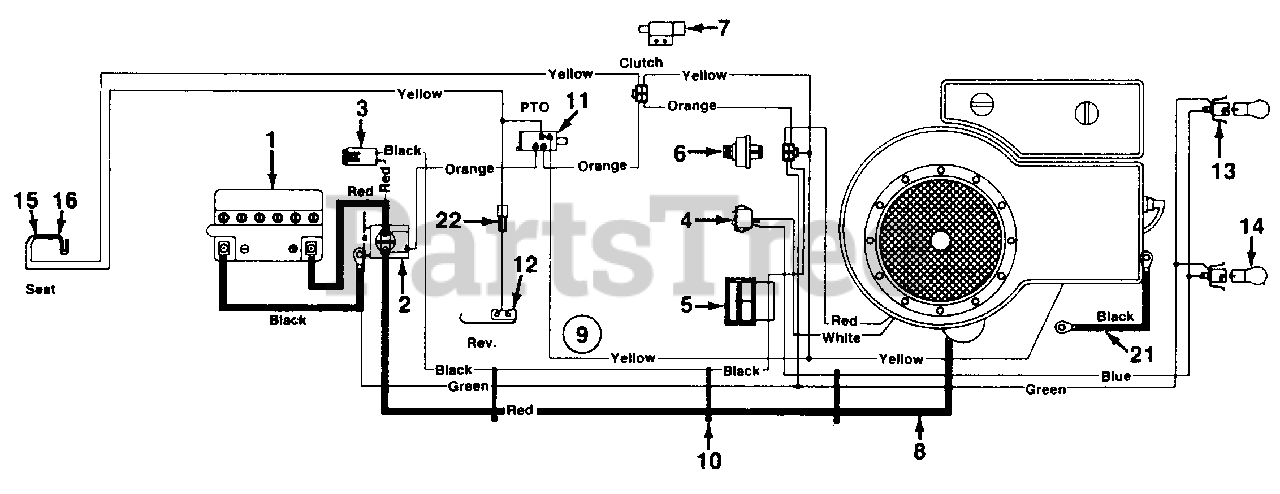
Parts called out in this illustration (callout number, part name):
1	Battery
2	Solenoid
3	Fuse 7.5 Amp
4	Light Switch
5	Ammeter
6	Ignition Switch
7	Safety Switch (Clutch)
8	Electric Wire 30" Lg.
9	Wire Harness
10	Cable Tie
11	Safety Switch (Deck)
12	Safety Switch (Reverse)
13	Twist Lock Bulb Socket
14	Bulb
15	Safety Switch (Seat)
16	Safety Switch (Seat)
21	Ground Wire 7.5" Lg.
22	Extension Wire
